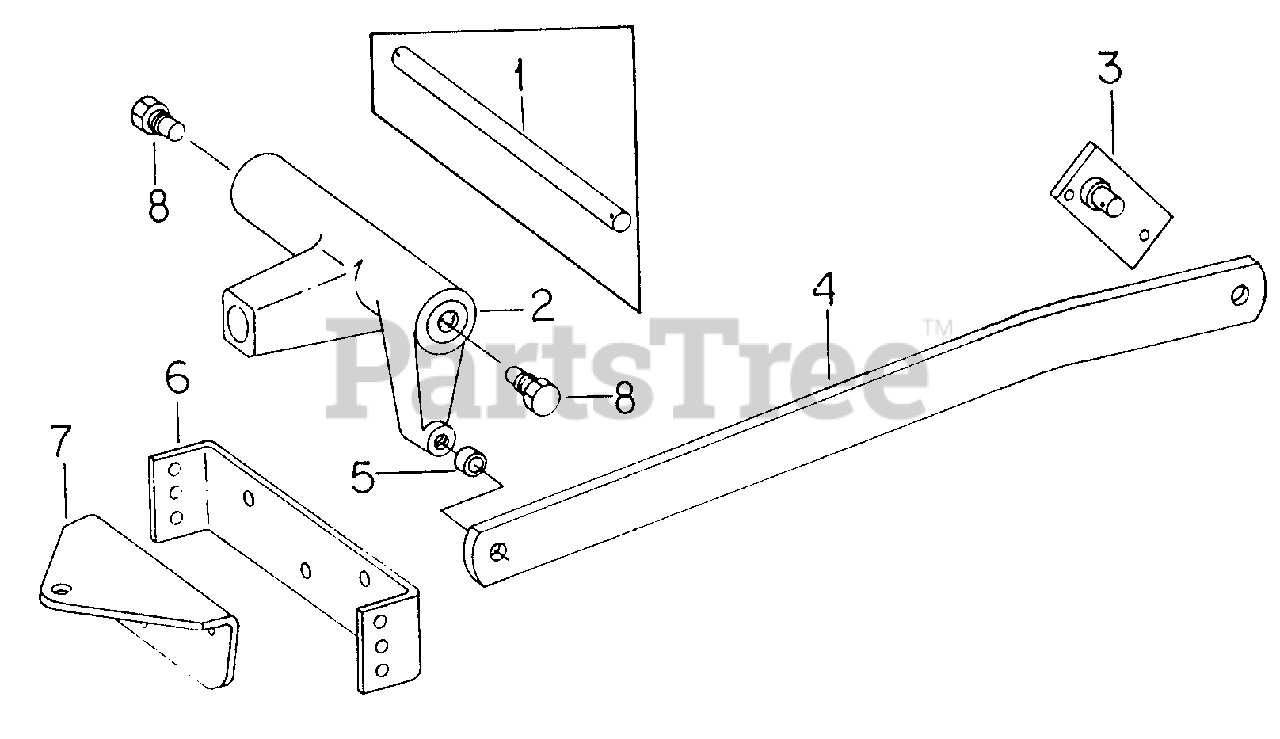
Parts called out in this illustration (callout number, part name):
1	Shaft, Lift Lever
2	Lever, Lift
3	Plate Assy, Lift Bar
5	Spacer, Lift Bar
7	Drawbar, Fixed
8	Bolt, Stud Shaft
